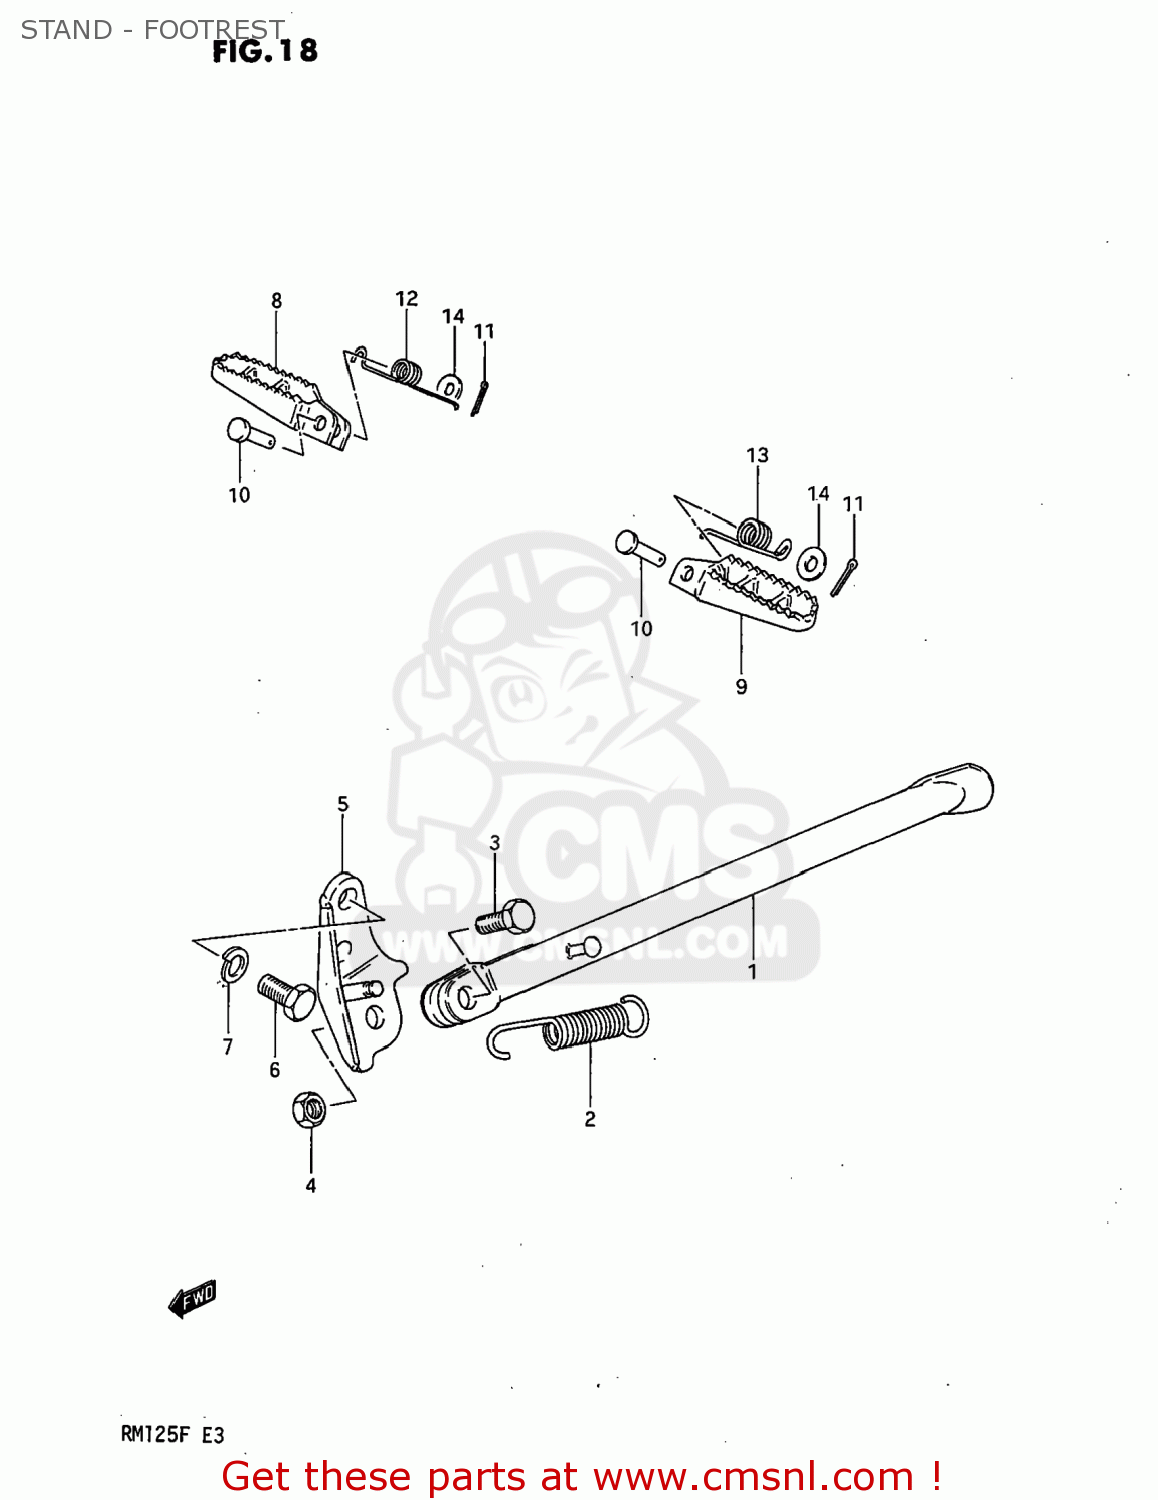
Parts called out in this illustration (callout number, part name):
1	STAND,SIDE
2	SPRING
3	BOLT(10X30)
4	NUT
5	BRACKET,SIDE STAND
6	BOLT(10X19)
7	LOCK WASHER
8	FOOTREST
9	FOOTREST
10	PIN
11	PIN 20X20
12	SPRING
13	SPRING
14	WASHER
